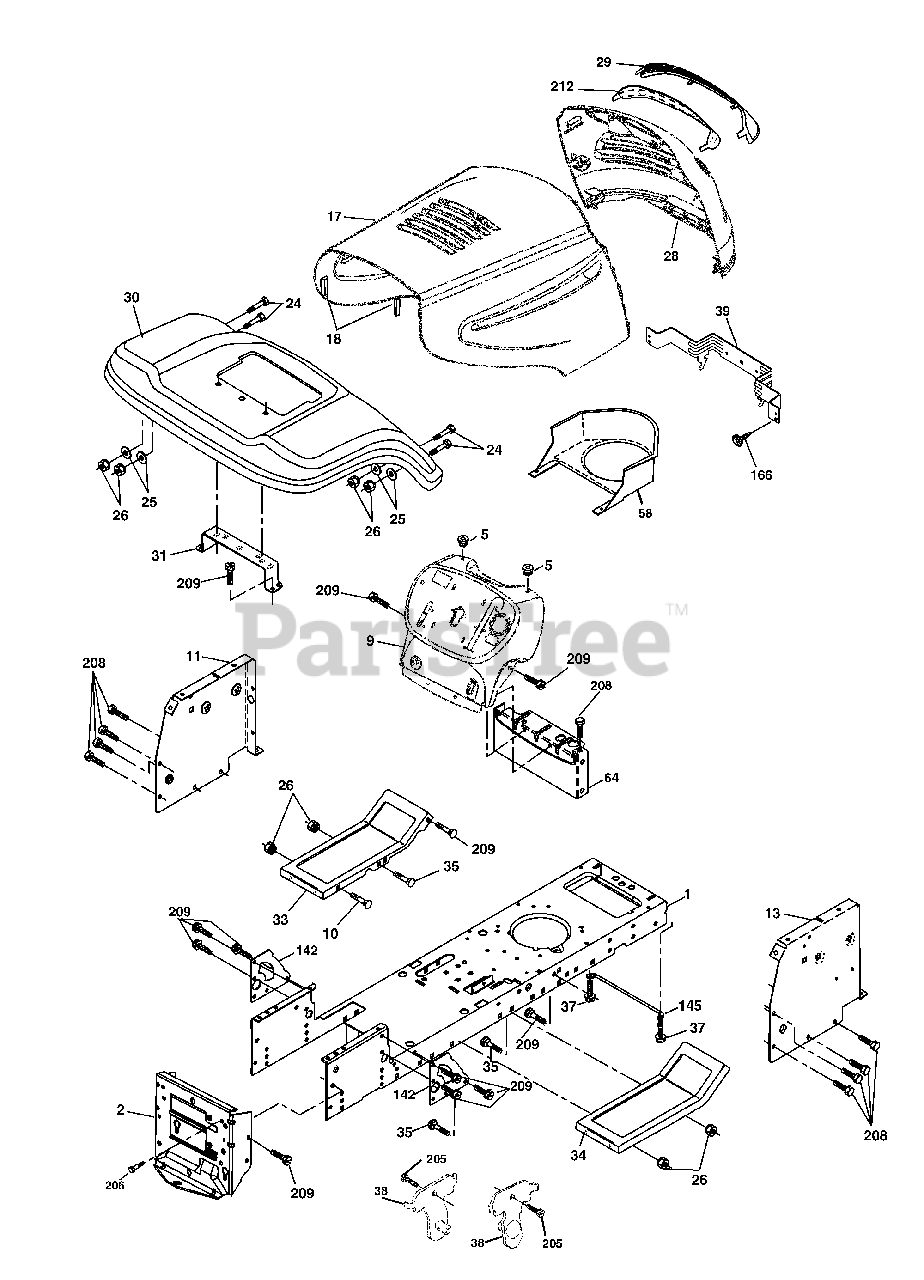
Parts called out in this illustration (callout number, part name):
1	Chassis
2	Drawbar
5	Bumper Hood/Dash
9	Dash
10	Bolt Carriage 3/8-16 x 1
11	Panel Dash Lh
17	Hood
18	Bumper Hood
24	Bolt Fin Hex 3/8-16 x 1 Gr. 5
25	Washer 13/32 x 13/16 x 12 Ga.
26	Nut Lock Hex W/Ins 3/8-16 unc
28	Grille
29	Lens
30	Fender Footrest STLT Pnt
31	Bracket Support Fender
33	Footrest Pnt Lh
34	Footrest Pnt Rh
35	Bolt Rdhd Sht Sqnk 3/8-16 x 3/4
37	Screw Thdrol 6/16-18 x 1/2 TYT
38	Bracket Asm. Pivot Mower Rear
39	Bracket Pivot
58	Duct Air
64	Dash Lower STLT
142	Plate Reinforcement STLT
145	Rod Pivot Chassis/Hood
166	Screw HWHD Hi-Lo #13-16 x 5/8
205	Screw Thdrol 3/8-16 x 1-1/4
206	Bolt Shoulder 5/16-18
207	Screw Thdrol 5/16-18 x 1/2
208	Screw Thdrol 3/8-16 x 1/2
209	Screw Hex Wsh Thdr. 3/8-16 x 3/4
212	Insert Lens Reflect
